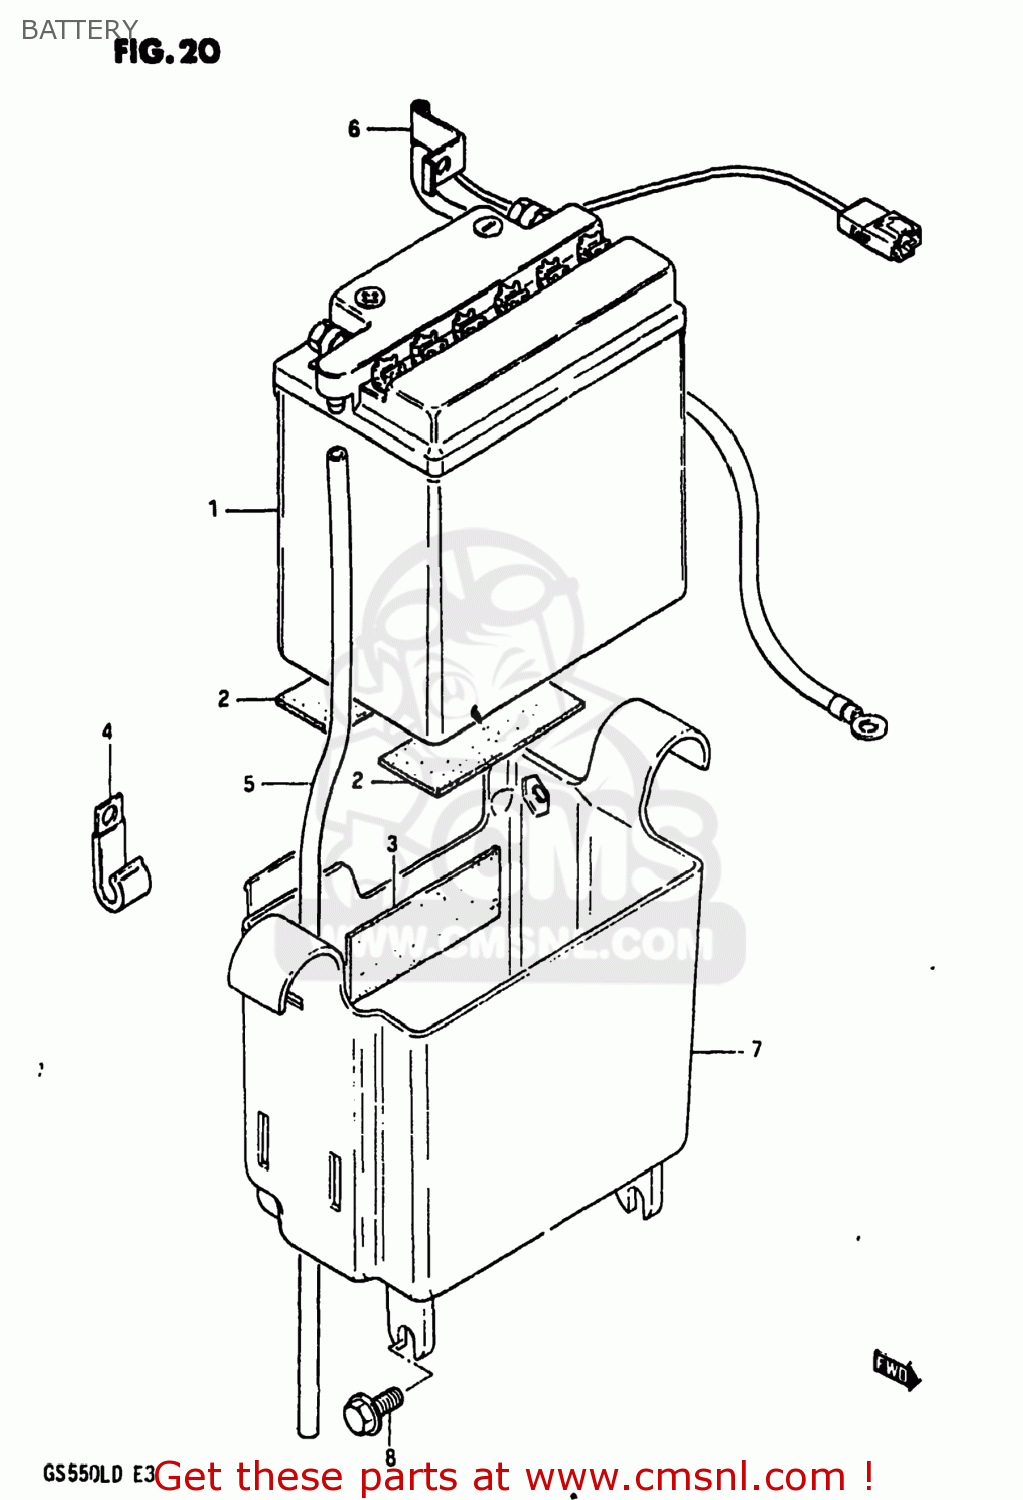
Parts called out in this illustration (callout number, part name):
1	BATTERY ASSEMBLY (12V)
2	PROTECTOR(30X80X2)
3	PROTECTOR,20X9
4	CLAMP
5	HOSE,BATTERY EXHAUST
6	CORD,BATTERY MINUS
7	HOLDER,BATTERY
8	BOLT
